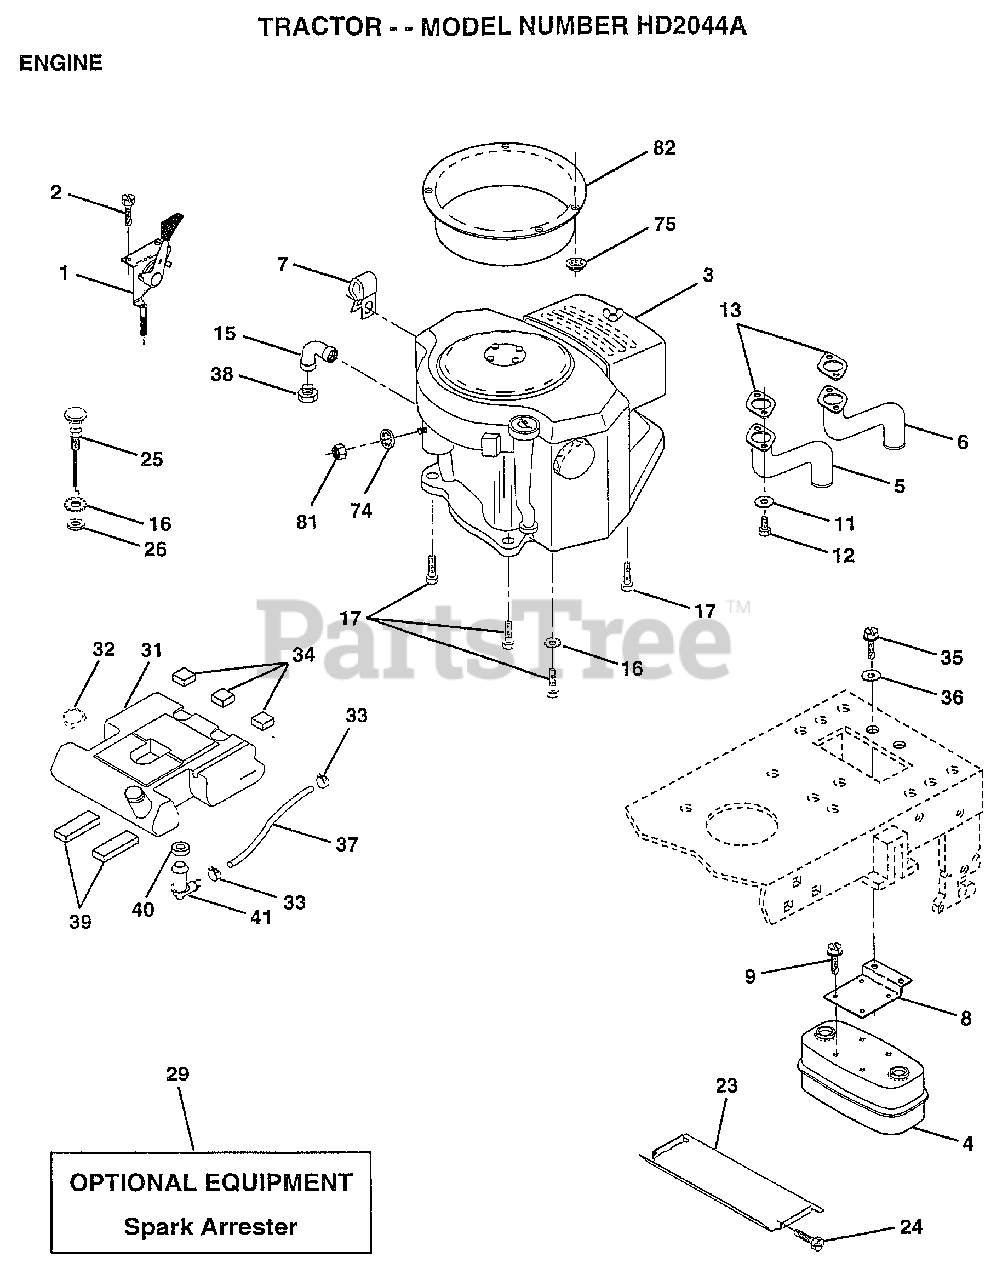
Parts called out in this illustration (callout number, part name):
1	CONTROL.THROTTLE
2	SCREW LT
5	TUBE MANIFOLD LH
6	TUBE MANIFOLD RH
7	CLAMP.TUBE.DBL.EN
8	BRACKET MUFFLER
9	SCREW ST
11	LOCKWASHER
12	SCREW
13	GASKET-MUFFLER )
15	STREET ELBOW LT
16	LOCKWASHER
17	SCREW LT
23	HEAT SHIELD
24	SCREW
25	CHOKE CONTROL
32	CAP ASM FUEL
33	HOSE CLAMP
34	PAD-SPACER LT
35	SCREW
36	WASHER
37	FUEL LINE T
38	PLUG T
39	PAD IDLER TI
40	BUSHING OUTLET T
41	STEM.TANK.FUEL
75	PAL NUT LT
82	DUCT.AIR.COMP.ONN
